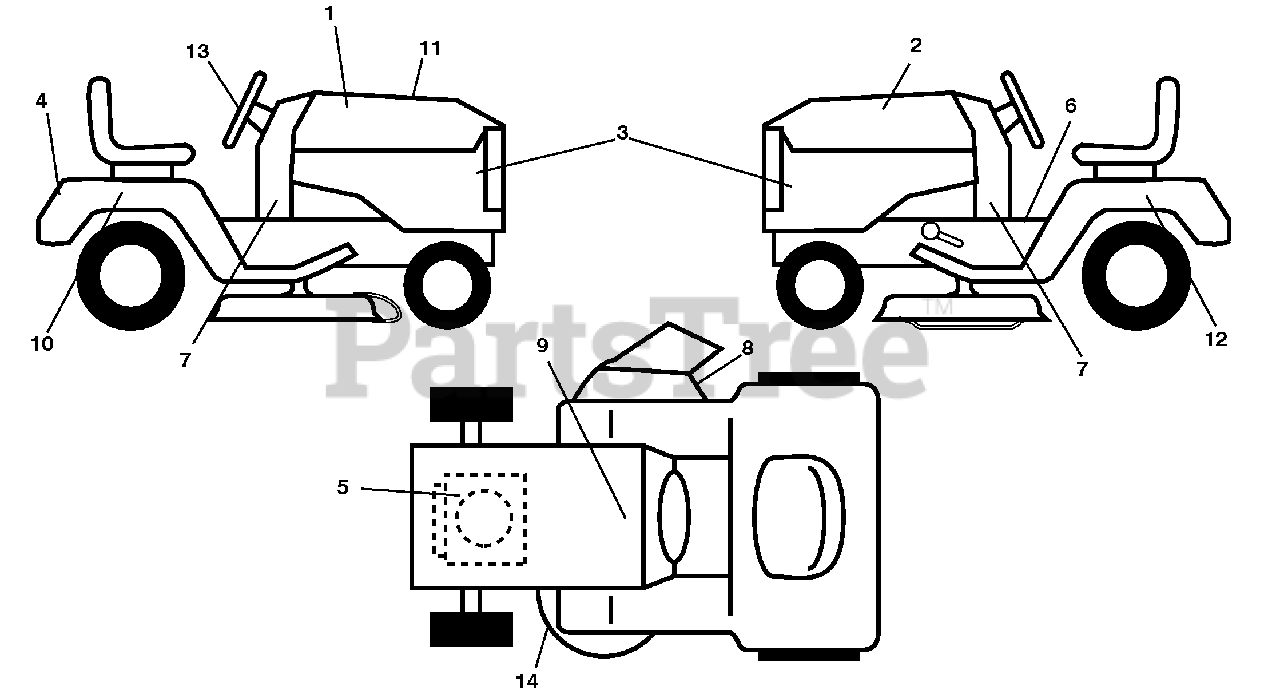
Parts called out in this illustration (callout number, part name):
1	Decal, Hood RH
2	Decal, Hood LH
3	Decal, Side Panel
4	Decal, Fender
5	Decal, Eng H.P.
6	Decal, Fender Operator's
7	Decal, Lower Dash
8	Decal, Warning
9	Decal, Battery Dnge/Poi
10	Decal, Fender SD RH
11	Decal, Replacement
12	Decal, Fender SD LH
13	Decal, Steering Wheel
14	Decal, Mower Schematic
14	Pad, Footrest Control
14	Decal, Bypass
14	Pad, Footrest, LH
14	Manual, Operator's (Eng/French)
14	Manual, Parts (Eng/French)
